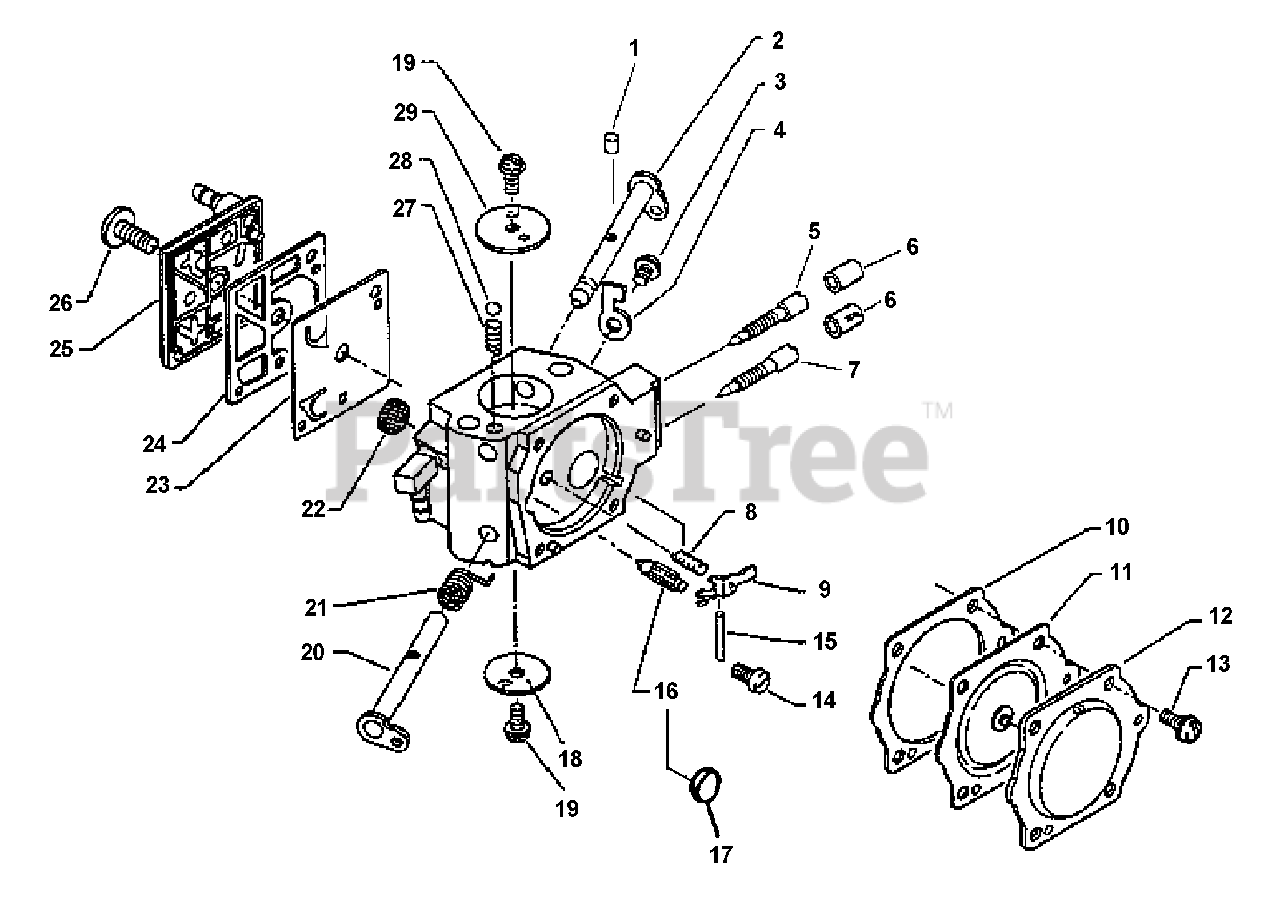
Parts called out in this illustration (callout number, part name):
1	PLUG, FRICTION
2	SHAFT, CHOKE
4	STOP, THROTTLE
5	NEEDLE - HIGH SPEED
6	CAP, LIMITER
7	NEEDLE - LOW SPEED
8	SPRING, METERING LEVER
9	LEVER, METERING
10	GASKET, METERING
11	DIAPHRAGM, METERING
12	COVER, METERING
13	SCREW
14	SCREW, METERING LEVER PIN
15	PIN, METERING LEVER
16	VALVE, INLET NEEDLE
17	PLUG, WELCH
18	VALVE, THROTTLE
20	SHAFT, THROTTLE
21	SPRING, THROTTLE RETURN
22	STRAINER
23	DIAPHRAGM, PUMP
24	GASKET, PUMP
25	COVER, PUMP
26	SCREW, PUMP COVER
28	BALL, CHOKE
29	VALVE, CHOKE
